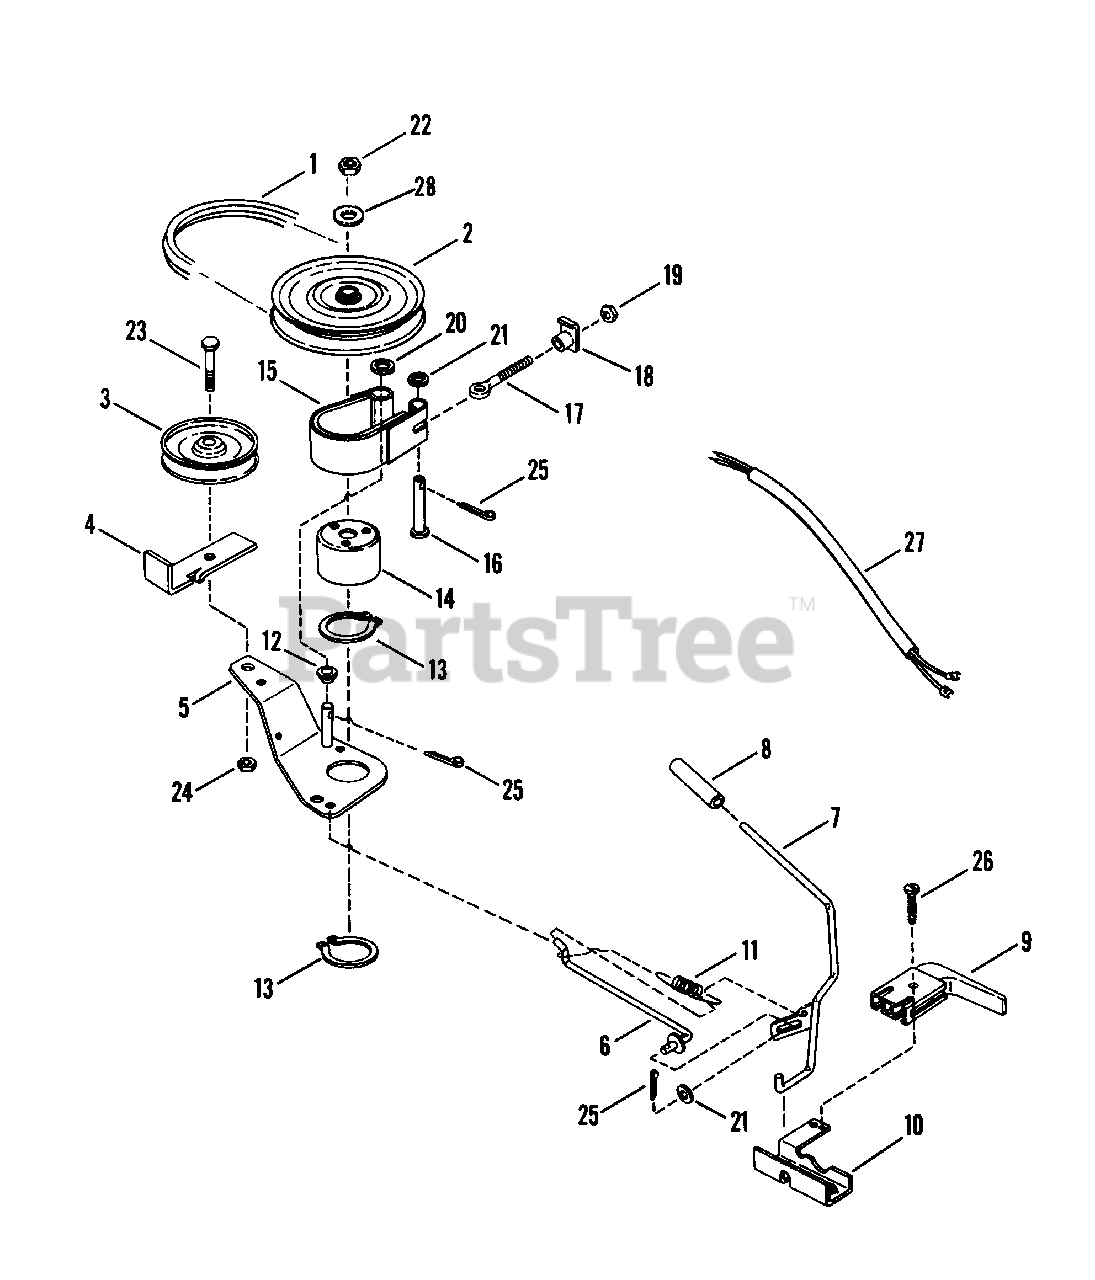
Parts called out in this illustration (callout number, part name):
1	BELT, Drive 28 & 30" Models
2	PULLEY, Spindle (Note: Also use 19520)
3	PULLEY, Idler
4	RESTRICTOR, Belt
5	ARM, Idler
6	ROD, Idler
7	HANDLE, Blade ON - OFF (Lever)
8	GRIP, Handle
9	SWITCH, Deck Interlock
10	MOUNT, Handle
11	SPRING, Blade Handle
12	SPACER
13	RING, 2" External Retaining
14	DRUM, Brake
15	BAND, Brake Assembly
16	PIN, 1/4 Clevis
17	EYE-BOLT
18	TEE-NUT
19	NUT, 1/4 Hex
20	WASHER, 3/8 SAE
21	WASHER, 1/4 SAE
22	NUT, 3/4-16 Hex Jam
23	CAPSCREW, 3/8-24x1 3/4" Hex head
24	LOCKNUT, 3/8-24
25	COTTER-PIN, 3/32x3/4"
26	SCREW, #10x1" Self-Tapping
27	HARNESS, Deck Interlock Wiring
28	WASHER, 49/64 Flat
